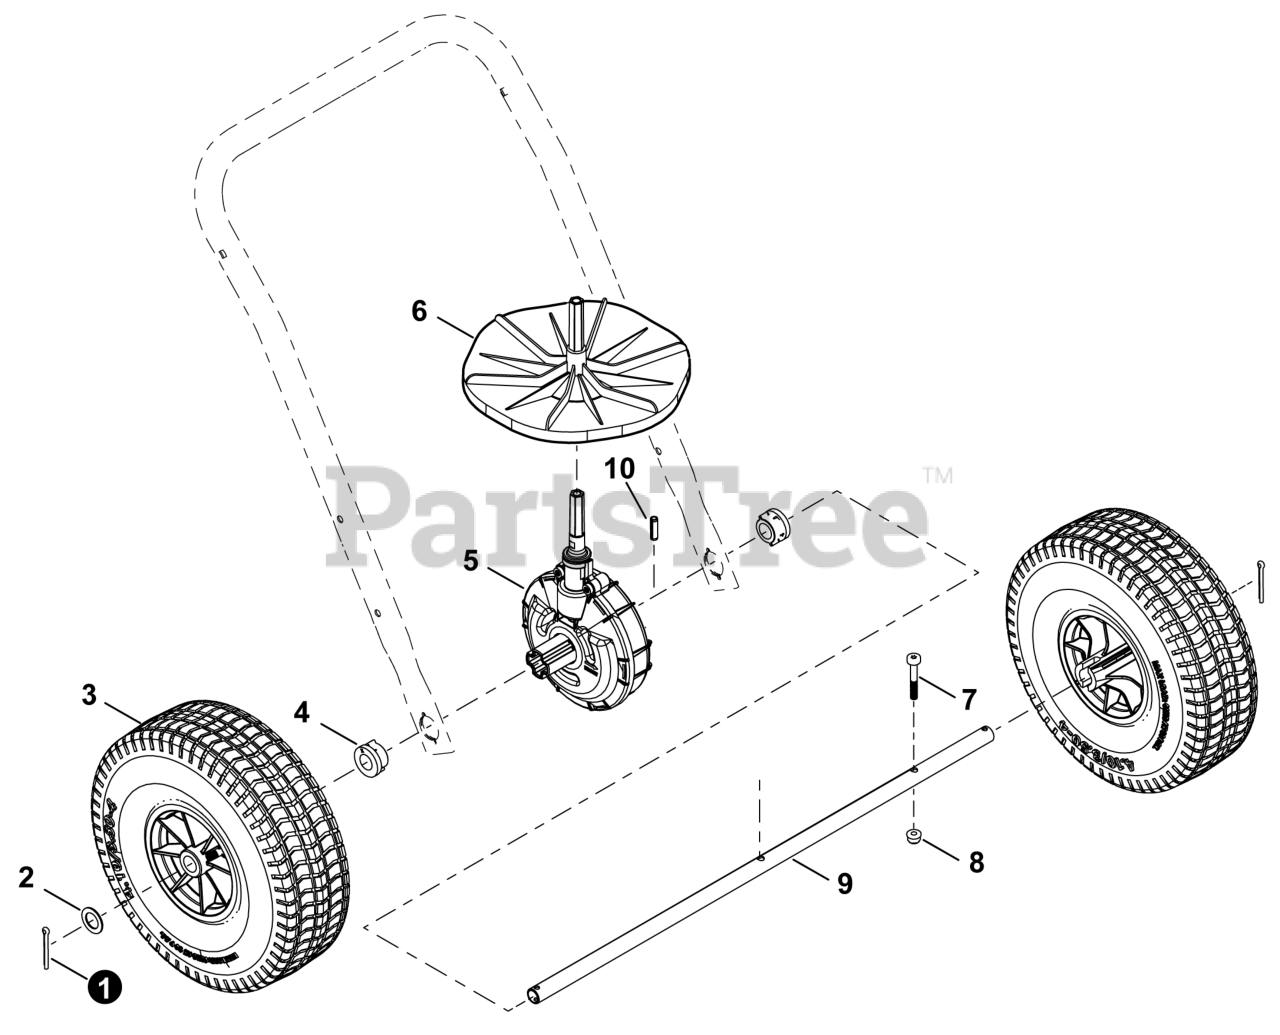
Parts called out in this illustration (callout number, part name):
1	PIN, CLEVIS
2	WASHER, CIRCULAR
3	WHEEL ASSY
4	BEARING, SHAFT
5	ASSY, GEAR CASE
6	IMPELLER
7	BOLT 6×40
8	NUT, FLANGE M6
9	DRIVESHAFT
